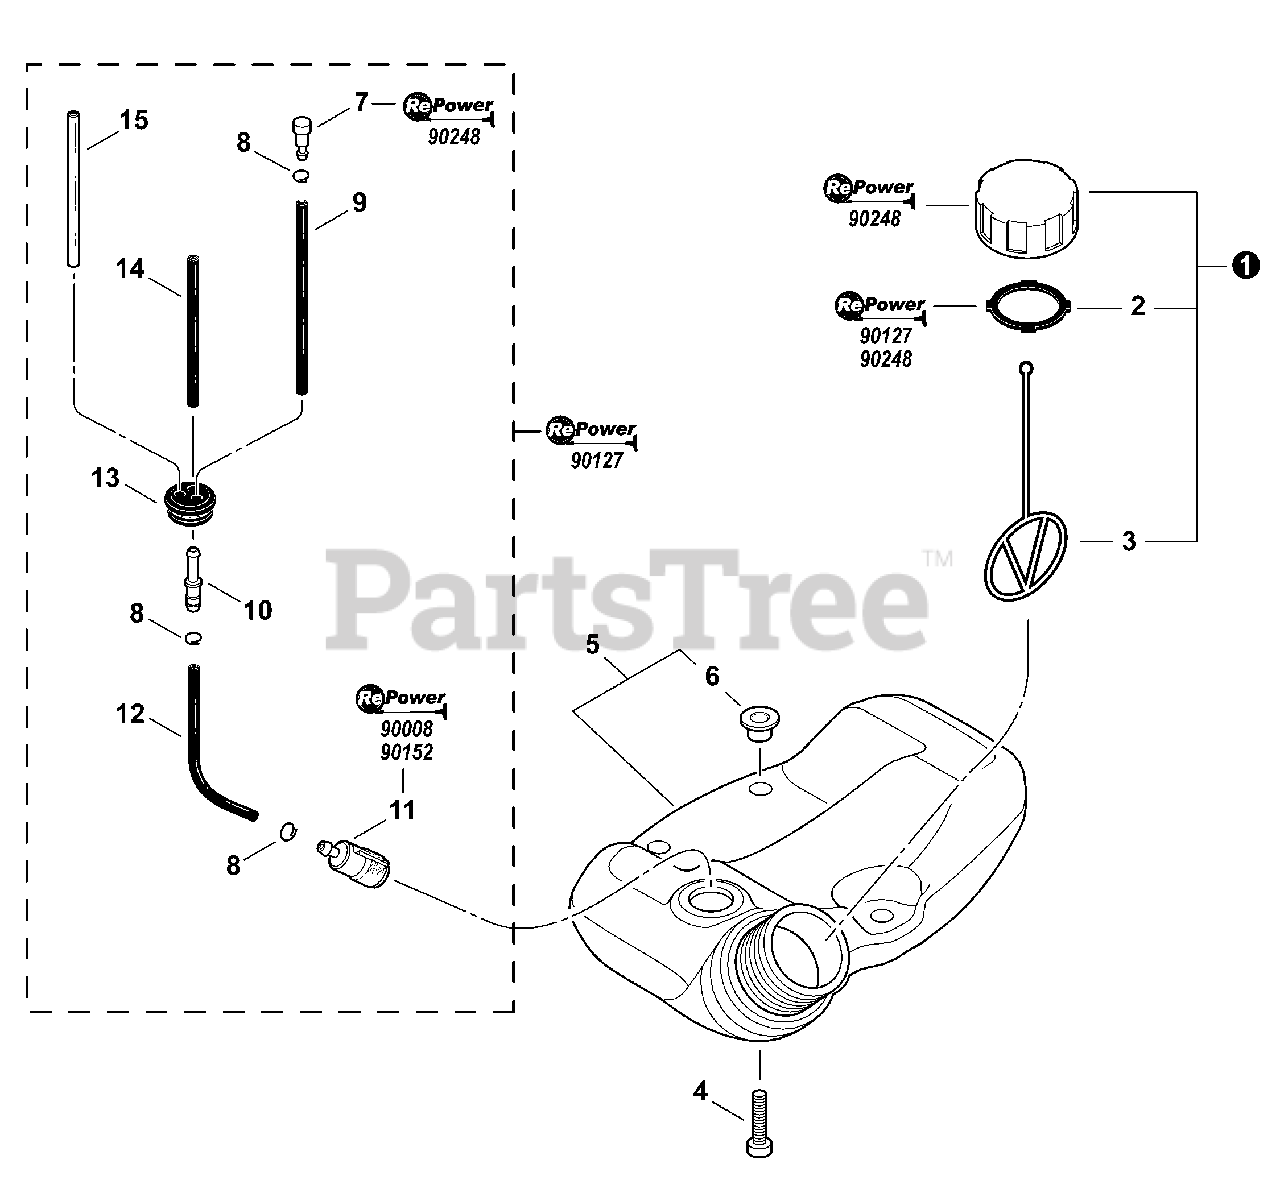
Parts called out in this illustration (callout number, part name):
1	CAP ASSY, FUEL
2	GASKET, FUEL CAP
3	CONNECTOR, CAP L= 123
4	BOLT, TORX 5×20
5	TANK ASSY, FUEL
6	COLLAR 5
7	VENT ASSY
8	CLIP Ø6
9	PIPE, FUEL 3×5×90 BLACK
10	CONNECTOR, PIPE Ø5ר3.5
11	FILTER, FUEL
12	PIPE, FUEL 3×5×130 BLACK
13	GROMMET, FUEL Ø5
14	PIPE, FUEL 3×5×74 BLACK
15	PIPE, FUEL 3×6×80 CLEAR
